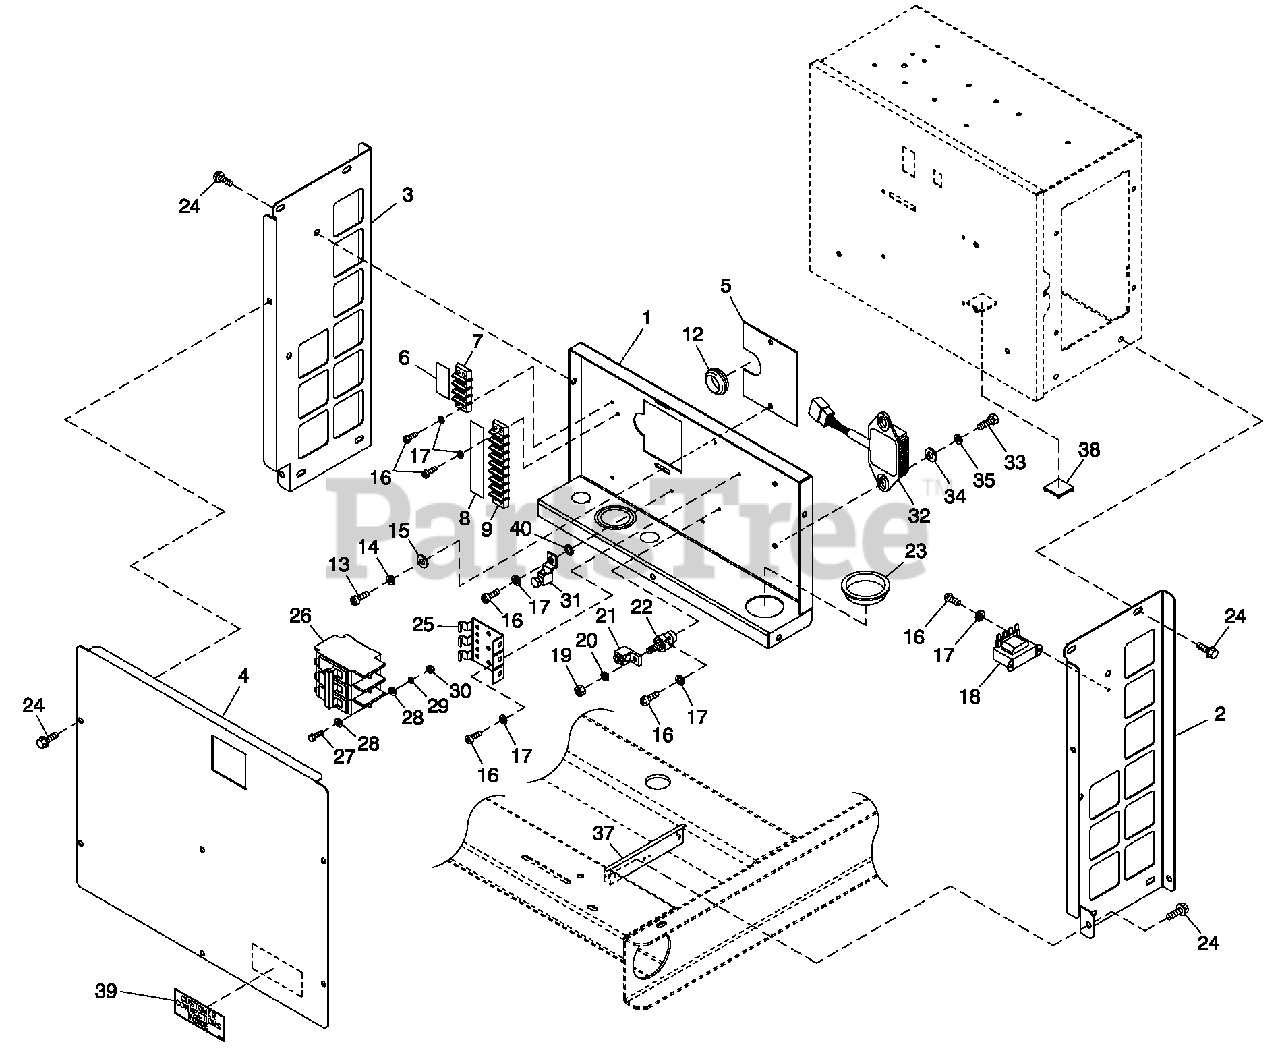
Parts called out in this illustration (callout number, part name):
1	BREAKER TRAY BACK/BOTTOM
2	SUPPORT CONTROL PANEL SIDE RH
3	SUPPORT CONTROL PANEL SIDE LH
4	COVER CIRCUIT BREAKER 2P
5	COVER CIRCUIT BREAKER 3P
6	DECAL CUST CONN 120V UTILITY
7	BLOCK TERM 20A 6 X 3 X 1100V
8	DECAL UTIL SENSE/CUST CONN
9	BLOCK TERM 20A 8 X 6 X 1100V
12	GROMMET 1.25 X .25 X .75
13	SCREW HHTT M5'0.8 X 12 BP
14	WASHER LOCK M5
15	WASHER FLAT M5
16	SCREW PHTT M4'0.7 X 16 ZYC
17	WASHER LOCK #8'M4
18	XFMR DUAL 104V/16V (3 PHASE)
19	NUT HEX 3/8'16 STEEL
20	WASHER LOCK 3/8
21	LUG SLDLSS 350'#6 X 13/32 AL/CU
22	JUNCTION BLOCK 3/8'16
23	BUSHING SNAP SB'2000'26
24	SCREW HWHTF M6'1.0 X 16
25	BRKT CB MTG BACK 2P
26	CB 0100A 2P 240V S BQ2 LL (1.5L 2 POLE)
31	LUG SLDLSS #6'14 X 13/64 CU
32	REGULATOR ' DC ALT
33	SCREW HWHTF M6'1.0 X 16
34	WASHER FLAT 1/4'M6 ZINC
35	WASHER LOCK M6'1/4
37	BRACKET PANEL SUPPORT 1.5L C1
38	CABLE TIE MOUNT BLACK
39	DECAL CUSTOMER CONNECT INSIDE
40	WASHER SHAKEPROOF EXT #10 STL
